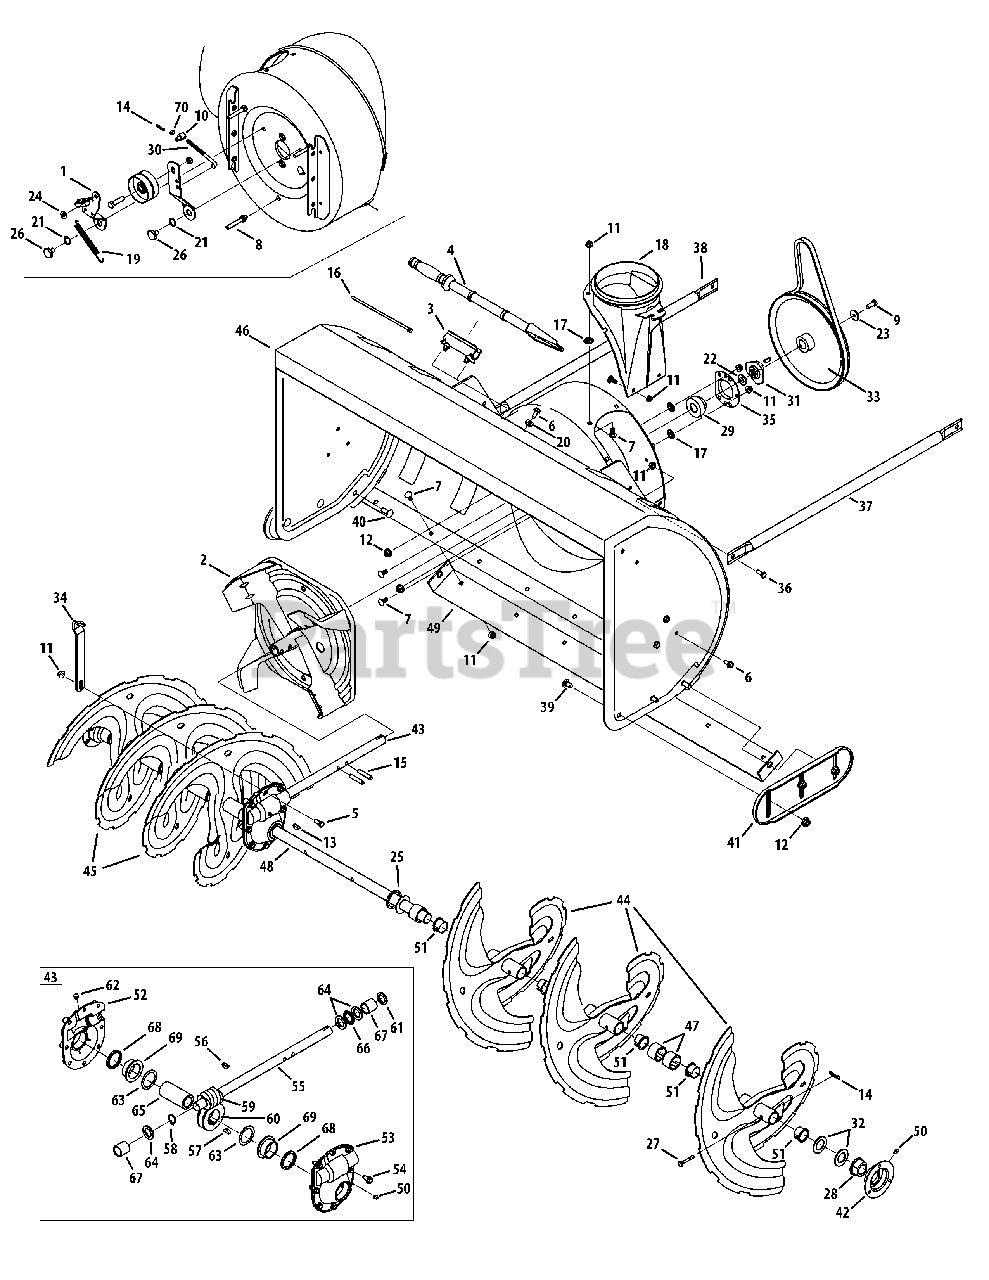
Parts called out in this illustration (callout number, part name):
1	Bracket Assembly, Auger Brake
2	Impeller , 16"
3	Clip, Mounting
4	Tool, Clean-out
5	Screw, Hex Cap, 5/16-18 x 1.0 Gr5
6	Screw, 5/16-18 x .750
7	Screw, Carriage, 5/16-18 x .75
8	Screw w/Stud, 5/16-18 x .4300
9	Screw, Hex Cap Lock, 5/16-24, 875
11	Nut, Hex Flange Lock, 5/16-18
12	Nut, Hex Flange Lock, 3/8-16
13	Key, Woodruff, 1/4 x 3/4
14	Pin, Bow-tie Cotter
15	Pin, Spiral, 5/16 x 1.75
16	Cable Tie
17	Nut, Push
18	Adapter, Chute, 6"
19	Spring, Extension
20	Washer, Flat, .349 x .879 .063
21	Washer, Wave, .625 x .885 x .015
22	Washer, Bell., .78 x 1.49 x .06
23	Washer, Flat, .34 x 1.5 x .15 Ht.
24	Washer, .344 x .75 x .12
25	Washer, 1.01 x 1.86 x .06
26	Screw, Shoulder, .625 x .17
27	Pin, Shear, .25 x 1.75
28	Bearing, Flange w/Flats
29	Bearing, Self Aligning
30	Rod, Auger Idler
31	Adapter, Pulley w/Pins
32	Spacer, 1.004 x 1.375 x .25
33	Pulley, Auger Drive, 10.0
34	Bracket, Gear Box Support
35	Housing, Bearing
36	Screw, 5/16-18 x .75 GR5
37	Tube, Support , LH
38	Tube, Support, RH
39	Screw, Carriage, 3/8-16 x .75
40	Screw, Carriage, 3/8-16 x 1.00
42	Housing, Bearing
43	Gear Box Assembly
44	Spiral Assembly, LH
45	Spiral Assembly, RH
46	Housing, Auger - 45"
47	Spacer, 1.50 x 1.00 x 1.00
48	Axle, Spiral
49	Shave Plate, 45"
50	Grease Fitting, 3/16
51	Flange Bushing
52	Housing Assembly, Auger, RH
53	Housing Assembly, Auger, LH
54	Screw, LD, 5/16-18 x .750
55	Auger Drive Shaft
56	Key, Hi Pro, 3/16 x 3/4
57	Key, 1/4 x 3/4 Dia.
58	External Retainer Ring
59	Gear, Worm
60	Gear, Worm, LH
61	Seal, Oil
63	Wash, Flat, 1.52ID x 2.0 OD
64	Wash, Flat, .88 ID x .38 OD
65	Worm Gear Shaft
66	Bearing, Thrust
69	Flange Bearing
70	Jam Nut, 5/16-18
